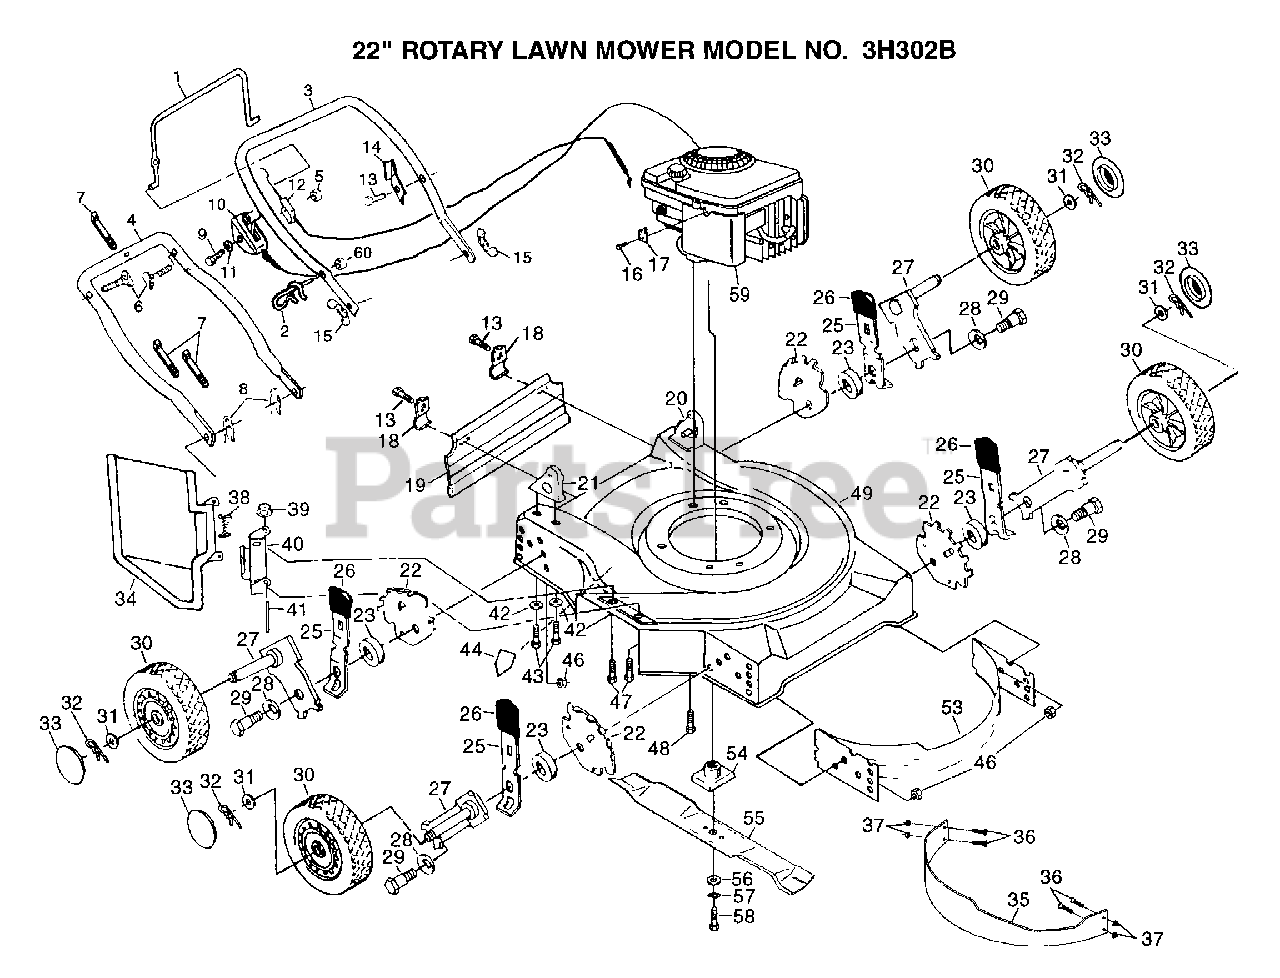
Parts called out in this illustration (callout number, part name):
1	CONTROL BAR
2	ROPE GUIDE
6	BOLT.HANDLE.LM
8	HAIRPIN COTTER
10	"CONTROL, THROTTLE"
11	WASHER PM
12	"CABLE,ENG ZONE CO"
13	TAPPING SCREW
14	"BRKT,UPSTOP"
15	"NUT,WING PM"
16	SCREW PM
17	CABLE CLAMP
18	"BRKT,DEFL PM"
22	BRACKET.ADJ.9POS.
25	SPRING SELECTOR
26	KNOB PM
27	AXLE ARM
28	"WASHER, BELLEVIL."
31	WASHER
32	RETAINER CLIP PM
33	HUB CAP
35	BAFFLE.MULCH.22SD
37	LOCKNUT
38	"SPRING,TORSION"
39	PUSH ON SPEED NUT
40	"BRKT,HSG"
41	"ROD,HINGE "
42	STEEL WASHER
43	SCREW
44	DECAL HYT
46	LOCKNUT PM
47	SCREW
48	SCREW
49	KIT.HSG.22SD.PUSH
53	BAFFLE.FRT/REAR
54	BLADE ADAPTOR
56	"WASHER,HARDEN"
57	LOCKWASHER
58	SCREW
60	NUT
